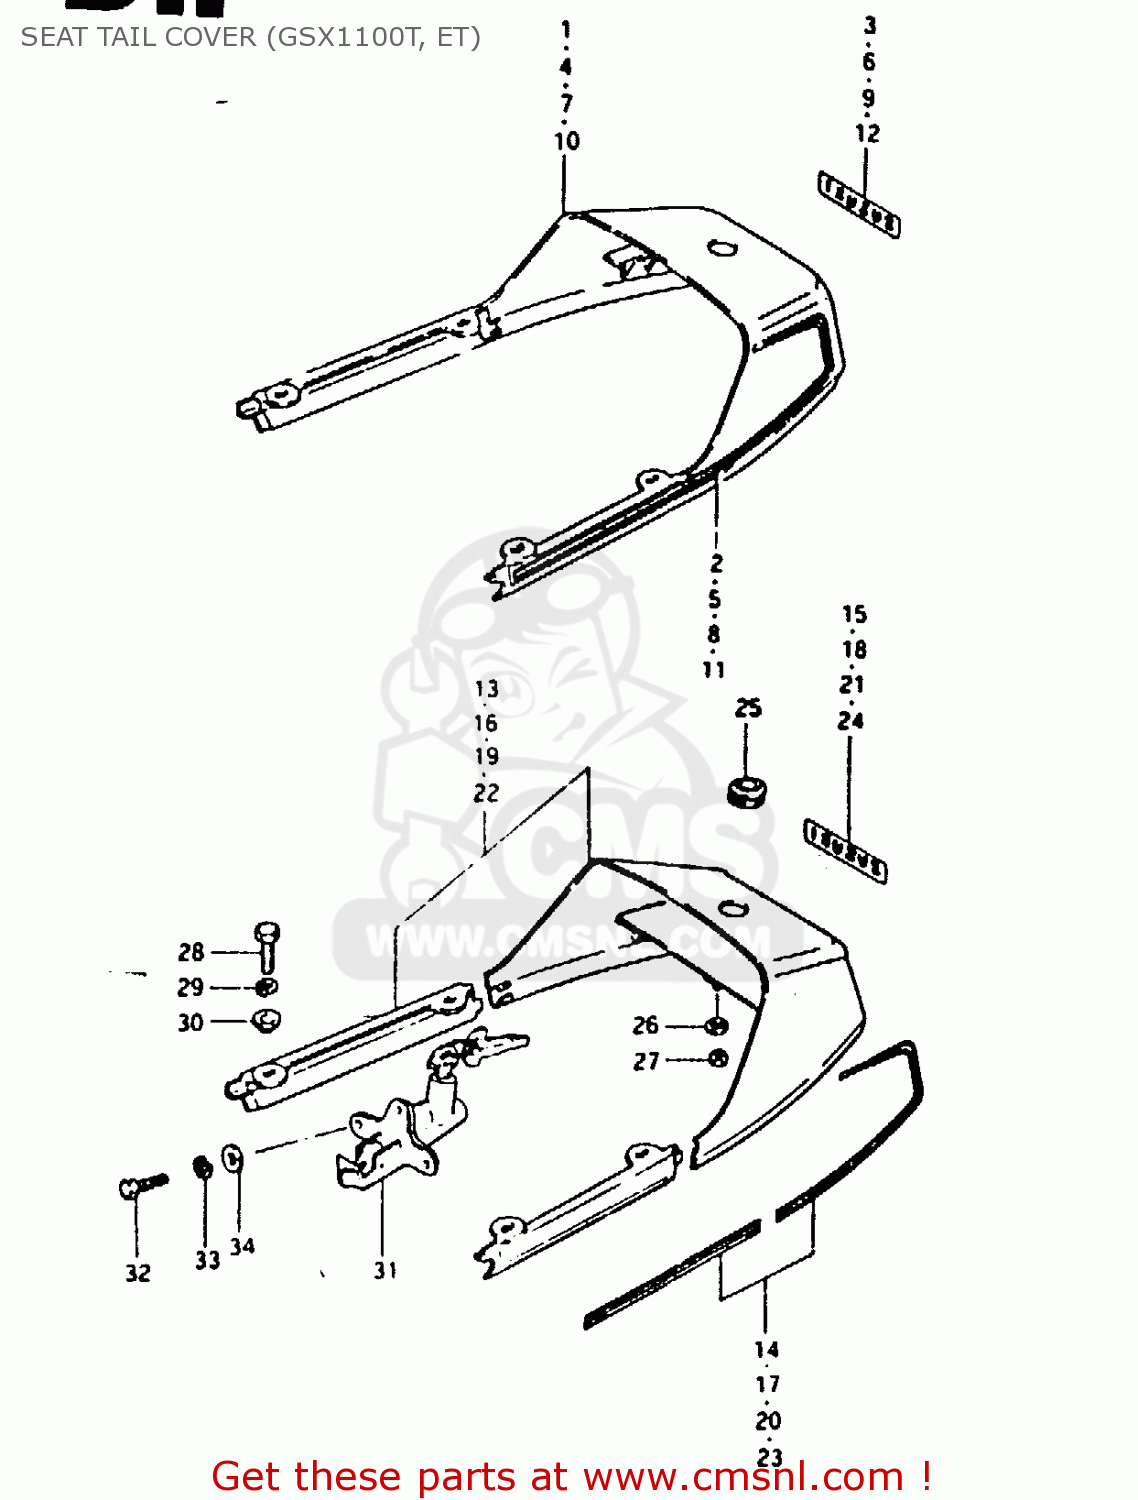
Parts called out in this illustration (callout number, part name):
1	TAIL COVER, SEAT
2	TAPE SET
3	EMBLEM (GOLD/BLACK)
4	TAIL COVER, SEAT
5	TAPE SET
6	EMBLEM,SEAT TAIL COVER
7	TAIL COVER, SEAT
8	TAPE SET
9	EMBLEM (GOLD/BLACK)
10	TAIL COVER, SEAT
11	TAPE SET
12	EMBLEM (GOLD/BLACK)
13	COVER SET, SEAT TAIL
14	TAPE SET
15	EMBLEM (GOLD/BLACK)
16	COVER SET, SEAT TAIL
17	TAPE SET
18	EMBLEM,SEAT TAIL COVER
19	COVER SET, SEAT TAIL
20	TAPE SET
21	EMBLEM (GOLD/BLACK)
22	COVER SET, SEAT TAIL
23	TAPE SET
24	EMBLEM (GOLD/BLACK)
25	GROMMET,SEAT LOCK HOLE
26	WASHER
27	NUT 6MM
28	BOLT
29	LOCK WASHER
30	WASHER
31	LOCK SET
32	BOLT
33	LOCK WASHER
34	WASHER
